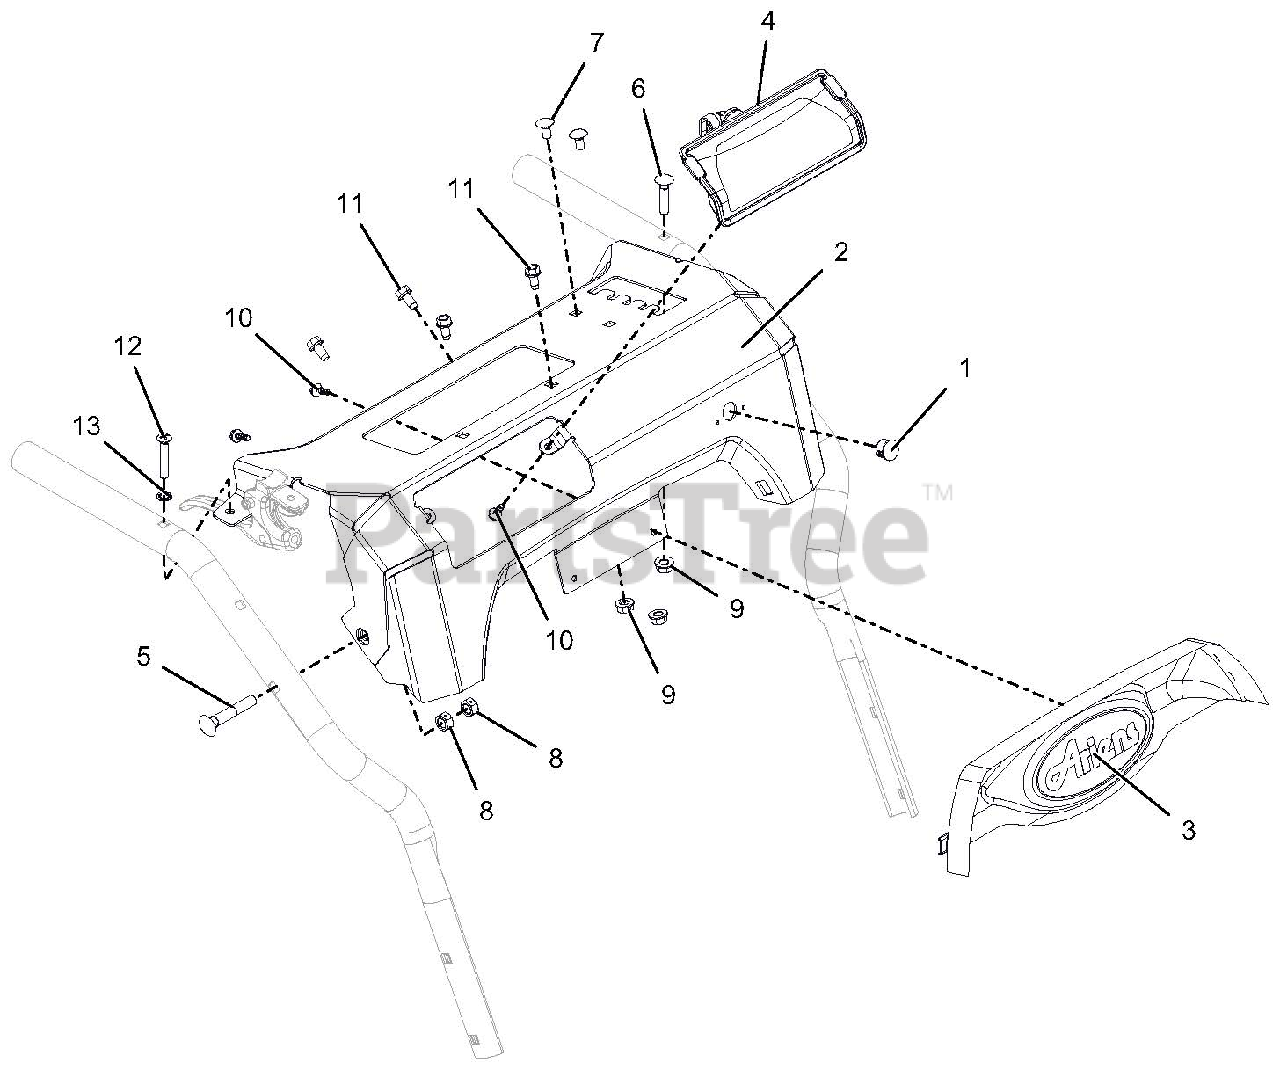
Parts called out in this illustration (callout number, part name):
1	HOLE PLUG, PLASTIC .56 HOLE
2	CONTROL PANEL W/DECAL, CMPT TK
3	DASH BEZEL, ARIENS LOGO - COMP
4	HEADLIGHT ASY, HALO 20W 2SHOT
5	BLT-RDHDXLSQNK .31-18X2.0 G5YZ
6	BLT-RDHDXLSQNK.25-20X1.25 G5ZC
7	@BLT-RDHDSQNK .25-20X.50 G5YZ
8	@NUT-LK-CTR .31-18 YWZC
9	@NUT-LK-TOP-FLG .25-20 YWZC
10	SCR-TAP #10X.50 BOSS INDHXHD
11	SCR-TAP .25-20X.50 HWH TR YWZ
12	SCR-MCH .25-20X1.50 OVAL HD
13	WSHR-LK-INT .250 TH TYA
